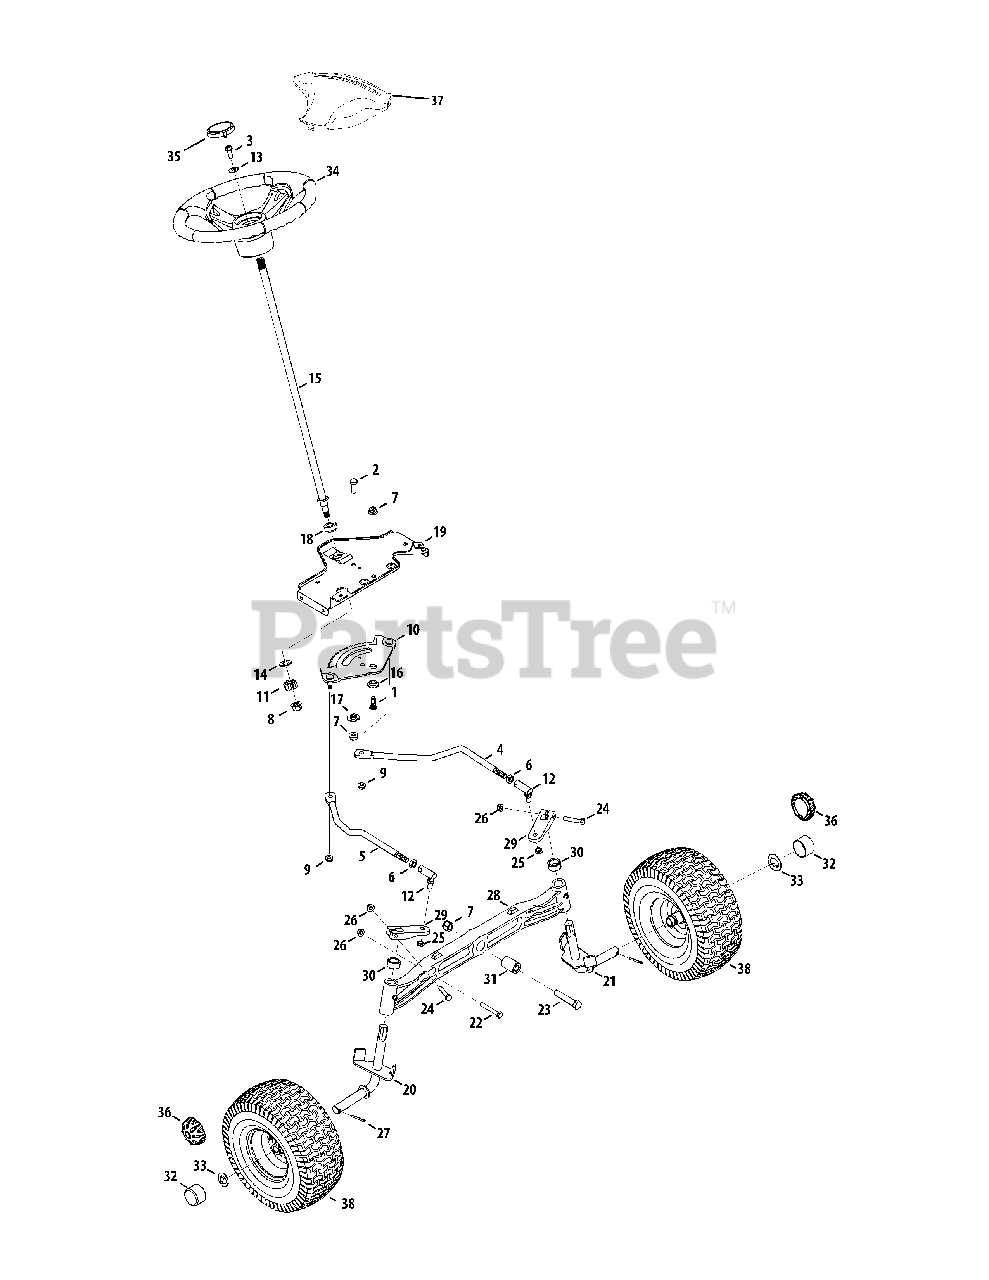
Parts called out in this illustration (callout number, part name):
1	Screw, 3/8-16 x 1.0
2	Hex Screw 3/16 x 1.00
3	Hex Screw 5/16-18 x 1.00 Special
4	Link, Drag LH
5	Link, Drag RH
6	Hex Jam Nut 7/16-20
7	Flange Lock-Nut 3/8-16 Gr. F Nylon
8	Flange Lock Nut, 7/16-20
9	Hex Flange L-Nut 5/16-18
10	Steering Gear, 11/90 Ratio
11	Steering Pinion Gear
12	Ball Joint, 7/16 - 20
13	Flat Washer .406 ID x .875 DE x .105
14	Fl. Washer .510 x 1.120 x .060
15	Steering Shaft .625 OD x 24.25
15	Steering Shaft .625 OD x 25.00
16	Shoulder Spacer .385 x 1.25 x .3025
17	Spacer .38x 1.375 Special
18	Hex Flange Bearing 5/8
19	Steering Support Bracket
20	Axle Ass’y RH .750 Dia. (46" Deck)
20	Axle Ass’y RH .750 Dia. (42" Deck)
21	Axle Ass’y LH .750 Dia. (46" Deck)
21	Axle Ass’y LH .750 Dia. (42" Deck)
22	Hex Bolt 5/16-18 x 2.25
23	Hex Cap Screw, 3/8-16 x 2.5
24	Hex Screw 5/16-18 x 1.75" Lg.
25	Hex Cent L-Nut 3/8-24
26	Flange Locknut 5/16-18 Gr. F, Nylon
27	Cotter Pin 5/32" Dia.
28	Pivot Bar (cast)
29	Steering Block
30	Spacer .710 ID x .125 OD x .56
31	Spacer .385 x 1.0 x 1.5075
33	Flat Washer .350 x 1.559 x .062
34	Steering Wheel, Standard Grip
34	Wheel Ass’y
35	Steering Wheel Cap (spig)logo
36	Hub Cap
37	Steering Wheel Cover (w/sprigs)
38	Wheel Ass'y Comp. 15 x 6 x 6
